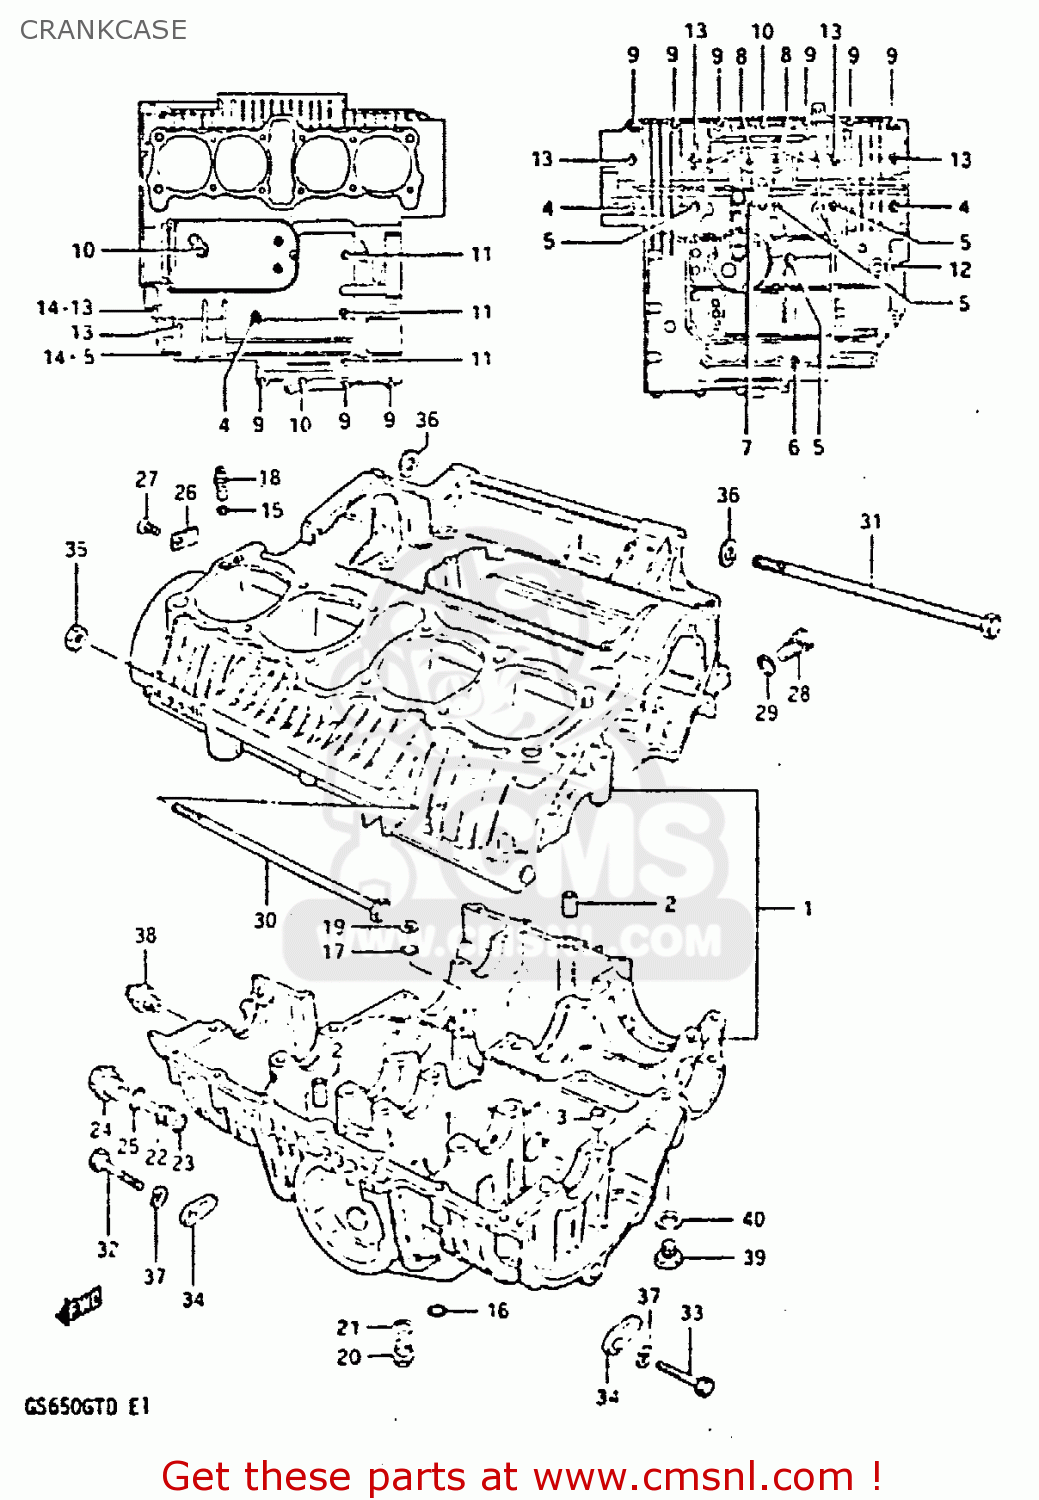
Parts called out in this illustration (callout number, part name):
1	CRANKCASE SET
2	PIN (11X20)(SUS)
3	PIN(10.4X13X22)
4	BOLT(8X110)
5	BOLT
6	BOLT(8X135)
7	BOLT(8X140)
8	BOLT
9	BOLT (6X40)
10	BOLT 6X55
11	BOLT (6X90)
12	BOLT (8X70)
13	BOLT (8X95)
14	NUT 8MM
15	O RING(D:1.2,ID:4)
16	O-RING
17	O RING(D:3.2,ID:12.9)
18	JET(12)
19	WASHER
20	PLUG
21	GASKET(16X22X2) (NAS)
22	PIN,OIL GALLERY
23	SEAL (D:1.9 ID:9.8)
24	PLUG
25	O RING(D:2.4,ID:17.8)
26	PLATE,OIL GALLERY PLUG
27	SCREW
28	PLUG
29	GASKET(12.1X16.2X3.7) (NAS)
30	BOLT
31	BOLT
32	BOLT 10X55
33	BOLT
34	NUT
35	NUT
36	WASHER
37	LOCK WASHER
38	SWITCH ASSEMBLY
39	PLUG
40	GASKET(14X19.2X2) (NAS)
